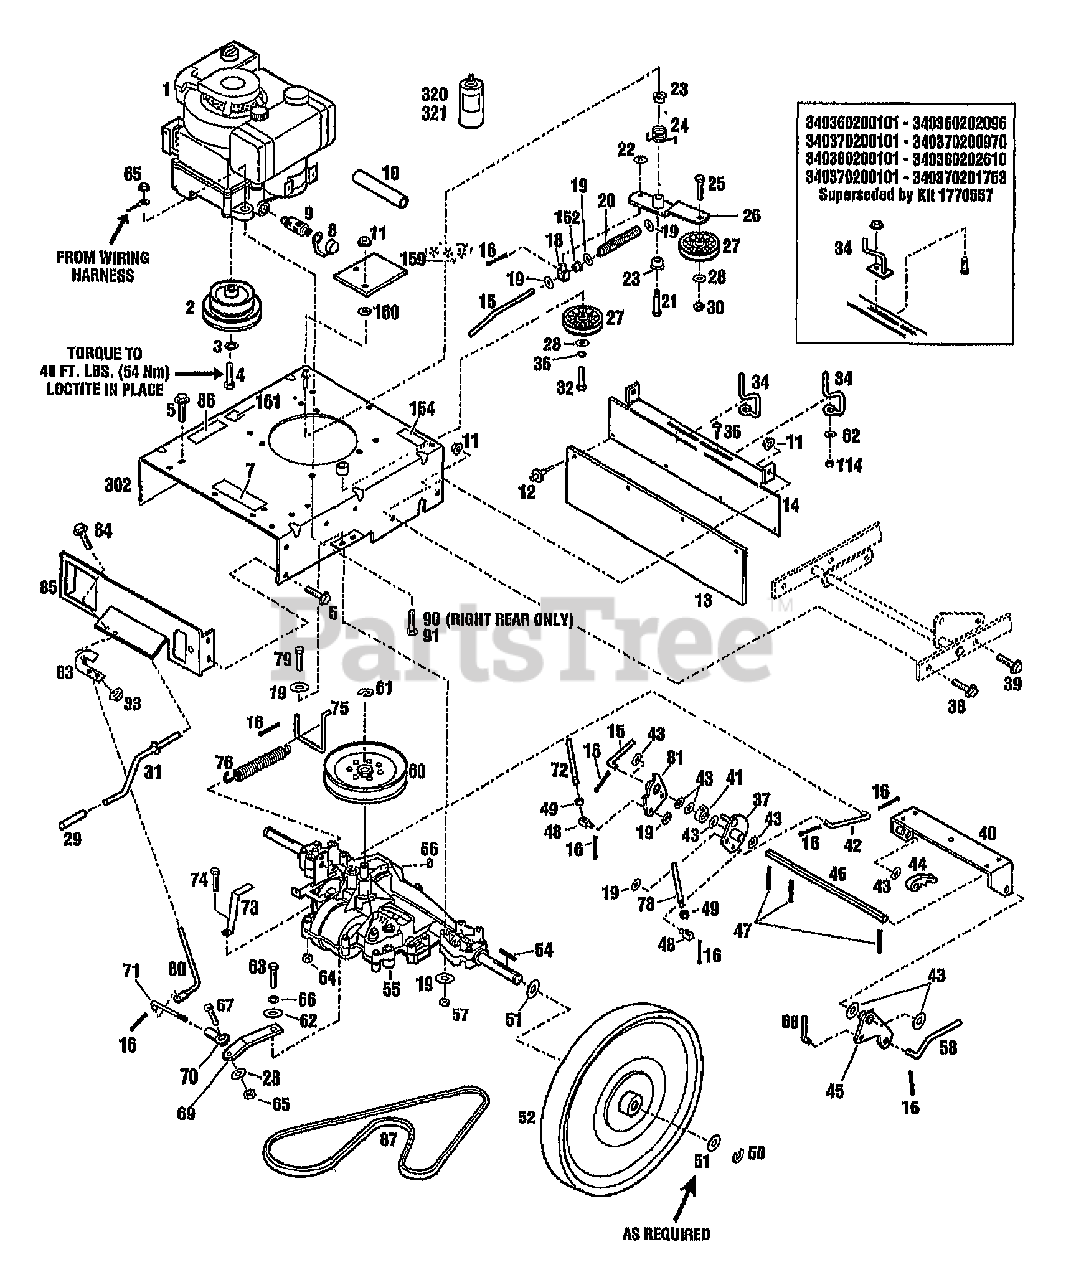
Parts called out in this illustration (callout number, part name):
1	ENGINE, 5.5HP ELEC.
1	ENGINE, 8HP,
2	ASSM-ENGINE SHEAVE-(SUPERSEDES 1764991)
3	WASHER-LK .438
4	SCR-HH 7/16-20X1.25 G5
5	SCR-HFLK 5/16-18X.62 G5
7	DECAL-WARNING
8	CAP-OIL DRAIN (INCL. 8)
9	ASSM-OIL VALVE
10	HOSE-OIL DRAIN
11	NUT-HFLK 3/8-16
12	RIVET-POP 3/16 X 5/8
13	FLAP-DEFLECTOR
14	BRACKET-FLAP MTG
15	ROD-LOWER TRANS
16	PIN-COTTER .093X.625
18	BLOCK-PIVOT
19	WASHER-FLAT 5/16 SAE
20	SPRING-COMPRESSION
21	SCR-SHLDR 3/8-16
22	WASHER-.632X.39X.0329
23	BUSHING-.5X.5 NYLON FLNG
24	SPRING-TORSION
25	SCR-CARR 3/8-16X1.75 G5
26	ASSM-IDLER ARM
28	WASHER-FLAT 3/8 SAE
29	GRIP-PLASTIC
30	NUT-LOCK 3/8-16
31	ASSM-CRANK LIFT
32	SCR-HH 3/8-16X1.75 G5
33	NUT-HF/LK 1/4-20
34	KIT-BELT GUIDE {34036,34037,34038,34039}
34	ASSM-BELT GUIDE {34036,34037,34038,34039}
35	SCR-CARR 1/4-20X.50
36	WASHER-LK .375 @ DEPL
37	ASSM-BRAKE ARM PIVOT
38	SCR-HFLK 3/8-16X1.25
39	SCR-HFLK 3/8-16X1.00
40	ASSM-PIVOT BRACKET
41	CAM-INTERLOCK
42	ROD-LOWER BRAKE
43	WASHER-FLAT 1.0X.516X.031
44	LATCH-INTERLOCK
45	ASSM-BLADE PIVOT ARM
46	SHAFT-PIVOT
47	PIN-COTTER .125 X .75
48	BLOCK-SWIVEL
49	NUT-HEX JAM 5/16-18
50	RING-RET."E".577 ID
51	WASHER-1.5X.755X.062
52	ASSM-WHEEL & TIRE
54	KEY-.188 SQ X 1.5
55	PEERLESS TRANSMISSION ASSEMBLY 915-022 (SEE GRID A-10/11 FOR BREAKDOWN)
56	KEY-WOODRUFF .188X.75
57	NUT-TOP/LK 5/16-18
58	ROD-LOWER
60	SHEAVE-TRANS DRIVE
61	RING-RETAIN .625 ID
62	WASHER-FLAT 1/4 SAE
63	SCR-HH 1/4-28X.75 G5
64	NUT-HFLK 5/16-18
65	NUT-H/LK 3/8-16
66	WASHER-LK .25
67	SCR-HH 3/8-16X1.25
68	ROD-UPPER BLADE
69	ARM-TRANSMISSION
70	JOINT-BALL
71	ROD-SHIFT LINK
72	ROD-UPPER TRANS MOWER
73	BRKT-BELT SUPPORT {34037}
74	SCR-HH 5/16-18X2.00
75	ROD-SPRING ATTACHMENT
76	SPRING-EXTENSION
78	ROD-UPPER BRAKE
79	SCR-HH 5/16-18X2.75 G5
80	ASSM-SHIFT LEVER
81	ASSM-CLUTCH ARM PIVOT
83	BRKT-SHIFT ROD MTG
84	SCR-HFLK 1/4-20X.50
85	PLATE-BACK
86	DECAL-WARNING THROWN OBJECT
87	BELT-TRANS DRIVE
90	SCR-THRD FRM 3/8-16X1.50 {34039}
91	SCR-HH 3/8-16X1.0 THDFM
114	NUT-HT LK 1/4-20
154	DECAL-AMERICAN LEGEND-SM
159	HEAT SHIELD
160	WASHER-FLAT 1.25X.406X.179 {34038,34039}
161	DECAL-STEP
302	ASSM-FRAME (INCL. 7 & 86)
320	PAINT-BLACK SPRAY
321	PAINT-RED SPRAYCAN POWDER
